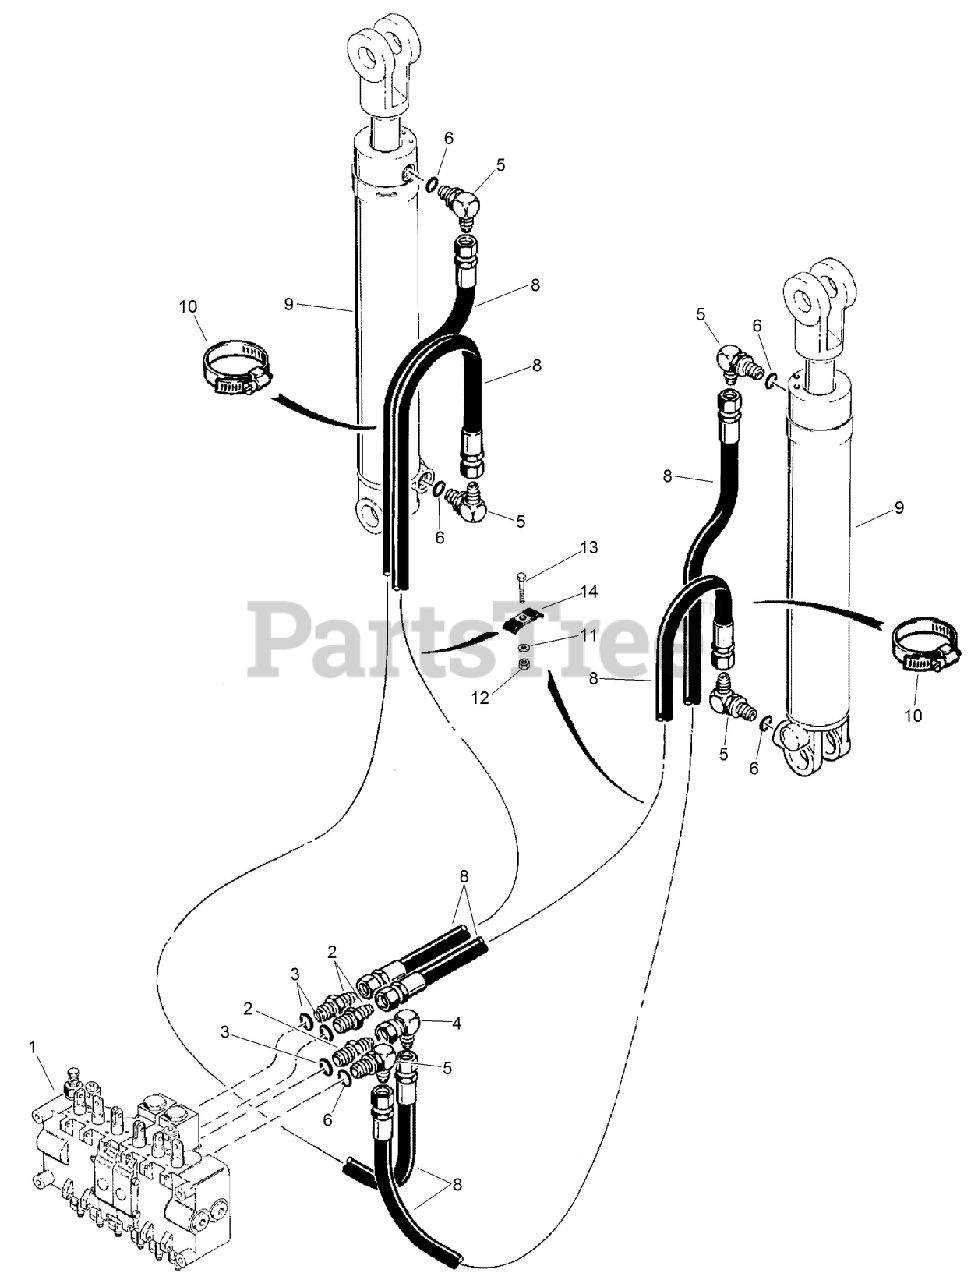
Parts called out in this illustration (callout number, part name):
1	VALVE-Backhoe, w/Special Low Leak Spools
2	CONNECTOR
3	O-RING
4	ELBOW-SWIVEL, 90 DEG
5	ELBOW-90 Adj 37FL, 3/8 x 1/2 Tube
6	O-RING
8	HOSE-1800 mm (70-7/8 inch) long, to stabilizer cylinders
9	HYD CYLINDER ASM
10	CLAMP-Hose #56
11	WASHER-Flat 5/16 HT
12	NUT-Prev Trq 5/16 GRA CAD NONDIR
13	BOLT-Hex, 5/16 NC x 1-1/2 inch
